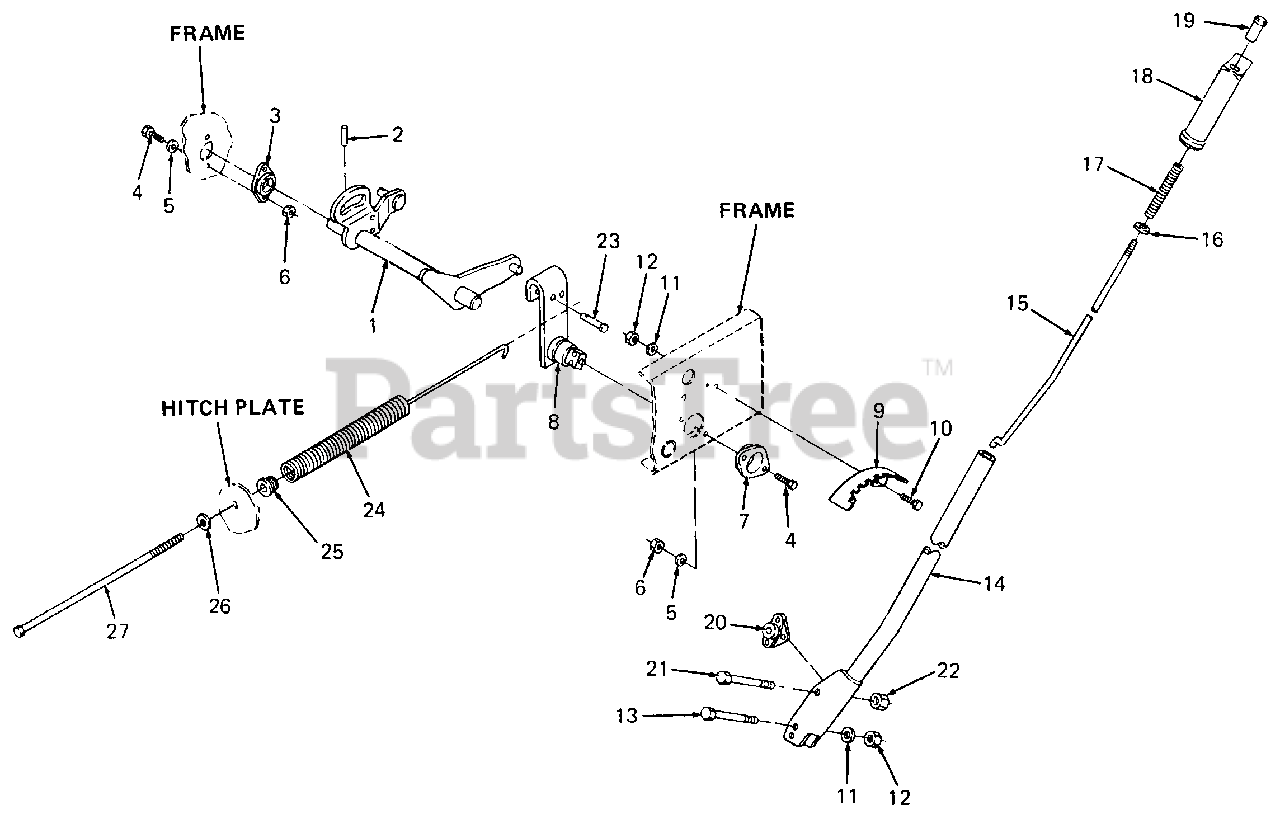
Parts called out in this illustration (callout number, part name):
3	Bushing, Lift, LH
4	Screw, Hex Cap, 1/4-20 X .75 Lg GR5
5	Washer, Lock, 1/4
6	Nut, Hex, 1/4-20
7	Bushing, Lift, RH
8	Bracket Assy, Lift
10	Screw, Hex Cap, 5/16-18 X .62 Lg
11	Washer, Lock, 5/16
12	Nut, Hex, 5/16-18
13	Screw, Hex Cap, 5/16-18 X 1.75 Lg GR5
16	Washer, Flat, .260 X .720 X .06 Thk
17	Spring, Lift Handle
18	Grip, Lift Handle
19	Button, Handle
20	Kit, Index Pawl
21	Screw, Hex, 3/8-24 X 1.62 Lg
22	Nut, Hex Center Lock Jam, 3/8-24
23	Pin, Clevis, 1/2 Dia X 2.19 Lg
24	Spring, Lift Assist, 1.03 ID X 17.0 Lg
25	Insert, Spring
26	Washer, Flat, .385 X .62 X .063 Thk
27	Screw, Hex Cap, 3/8-16 X 13.0 Lg
